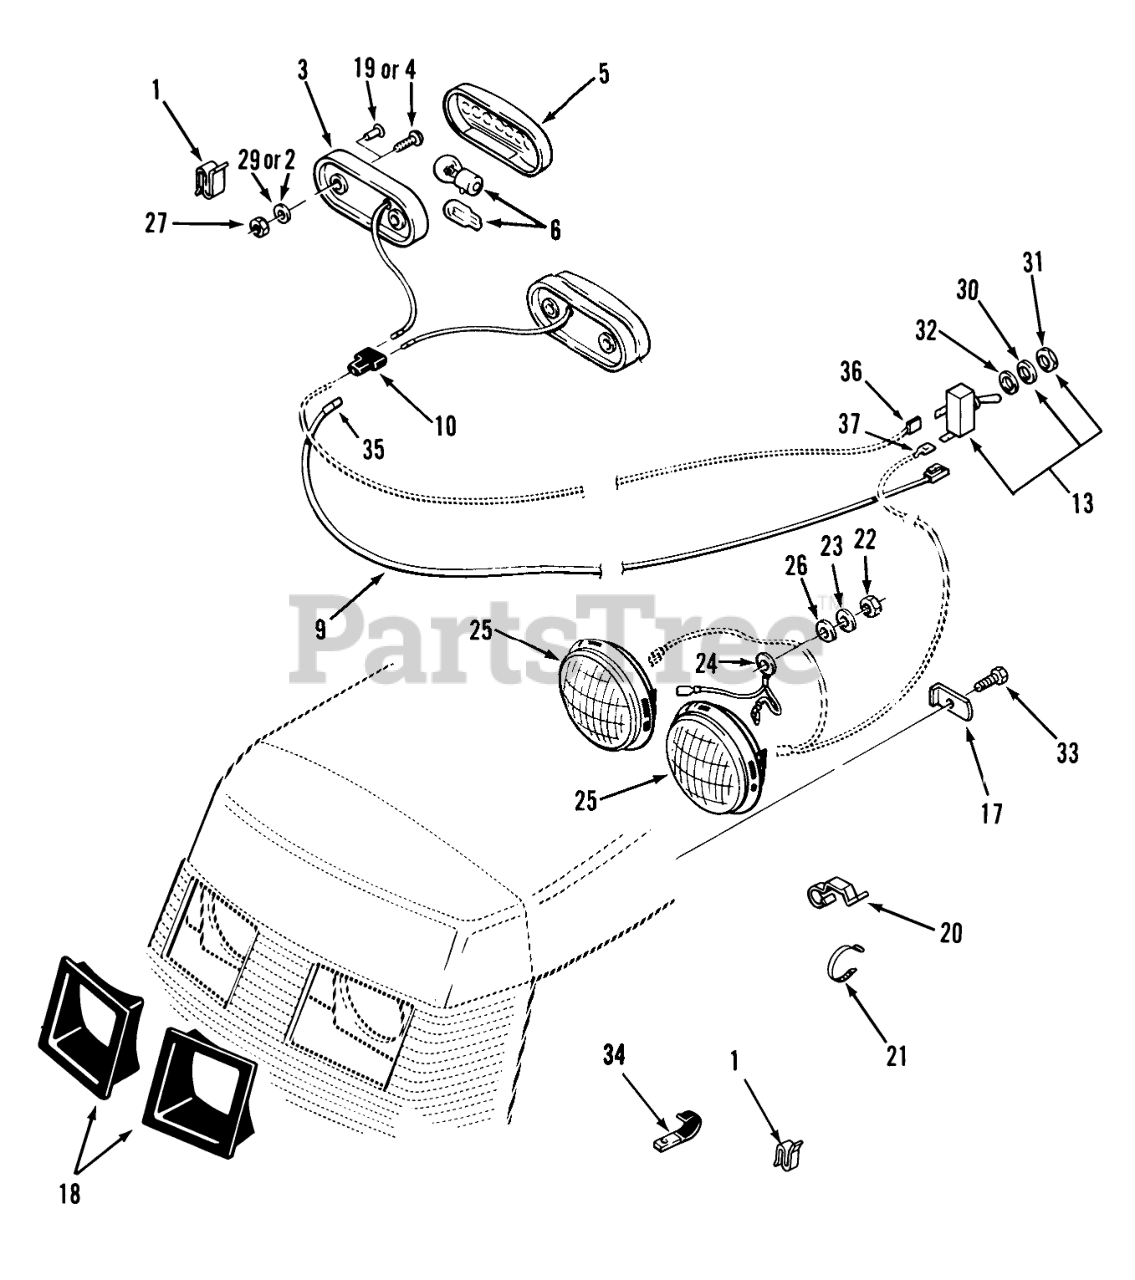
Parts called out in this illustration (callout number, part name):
1	SPEED CLIP
2	Lockwasher
3	BASE-TAIL LIGHT
4	Screw
5	LENS-TAIL LIGHT
6	Bulb
6	Light Bulb All Glass (Auto #194)
9	WIRE TAIL LIGHT
10	Connector 3-Wire
13	SWITCH-LIGHTS
17	LOCK-HEADLIGHT
18	HEADLIGHT BEZEL ASSY.(SERVICE)
19	RIVET-4
20	CLIP-WIRE
21	PLASTIC TIE
22	Nut
23	Washer-Lock
24	LIGHT GROUND WIRE
25	HEADLAMP
26	WASHER 5/16 SAE
27	Nut
29	WASHER
30	TAB-WASHER
31	NUT-HEX
32	Washer
33	Bolt
34	CLIP
35	Sur-Plug
36	TERMINAL 10
37	Terminal
